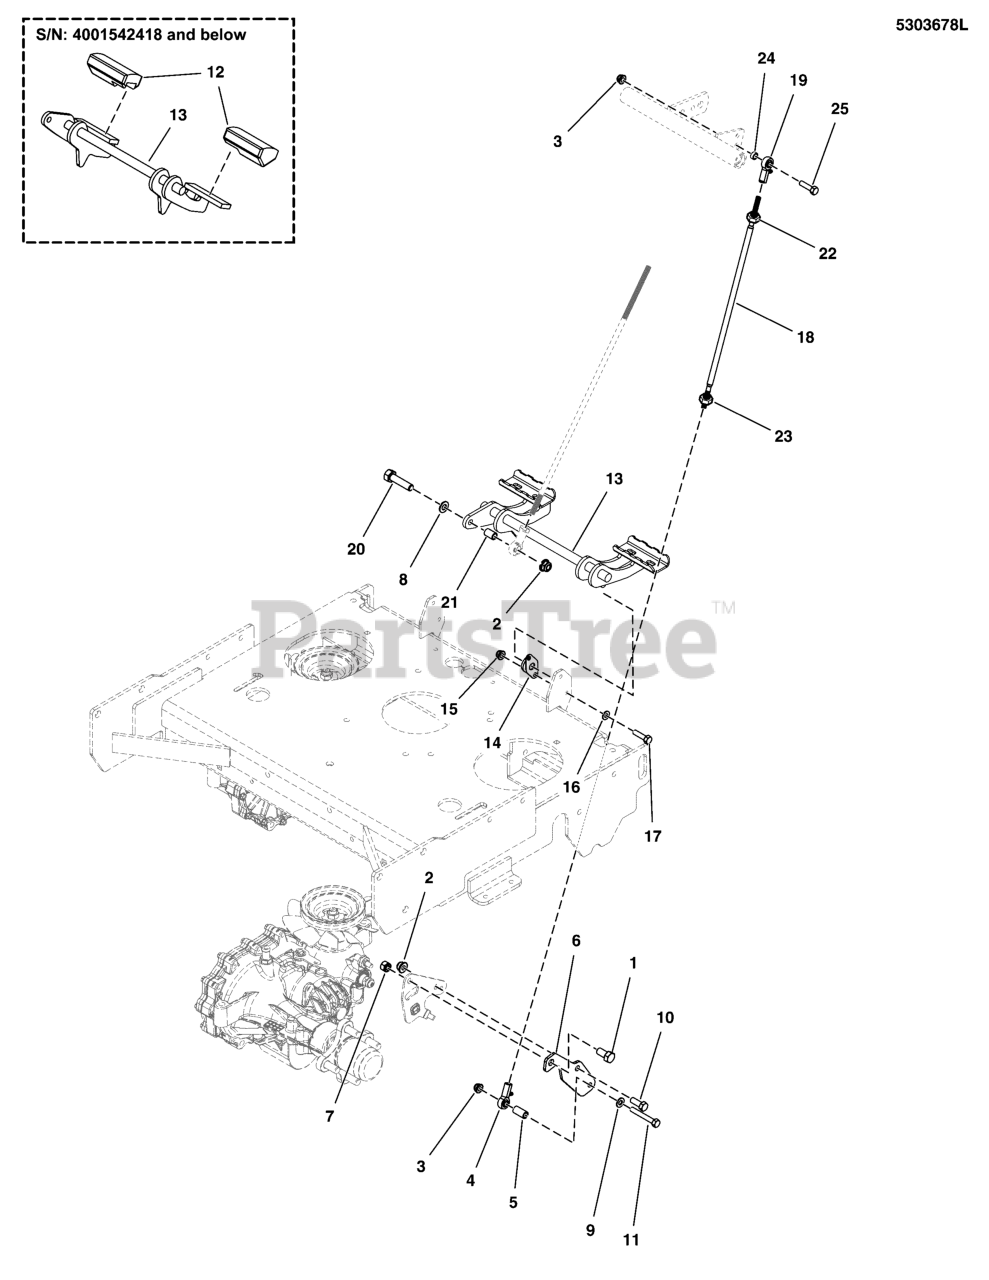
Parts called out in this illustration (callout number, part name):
1	BOLT, 7/16-14 X 3/4, GD 5 YZ
2	NUT, 3/8 - 16 HEX NYLOCK FLANGE
3	NUT, 5/16-18 HEX NYLOCK FLANGE NUT
4	BALL JOINT 5/16-24 RH FEMALE BRONZE RACE
5	SPACER, .33 X .51 X 1.00, CZ
7	NUT, 7/16-14 HEX TOP LOCK
8	WASHER, 3/8 SAE
9	WASHER, 5/16" SAE
10	BOLT, 3/8-16 X 1" GD5 CZ
11	* BOLT, 5/16-18 X 2-1/4 GD5 YZ
12	PEDAL, Rubber
13	WELD, FOOT PEDAL - BLK
14	BEARING, 5/8" FLANGED, PLASTIC BALL
15	NUT, 1/4-20 Hex Nylock Flange
16	WASHER, 1/4 SAE
17	HHCS, 1/4-20 X 0.625, GR5, ZINC/CLEAR
18	ROD, 5/16-24 X 15.48, LH-RH, CZ
19	BALL JOINT 5/16-24 LH FEMALE BRONZE RACE
20	BOLT, 3/8-16 X 2, GD5, CZ
21	SPACER, .38 X .50 X .50, YZ
22	NUT, 5/16-24 HEX, LH
23	NUT, Hex, 5/16-24
24	SPACER, .33 X .50 X .25, PM, CZ
25	BOLT, 5/16-18 X 1-1/4" GD5 YZ
